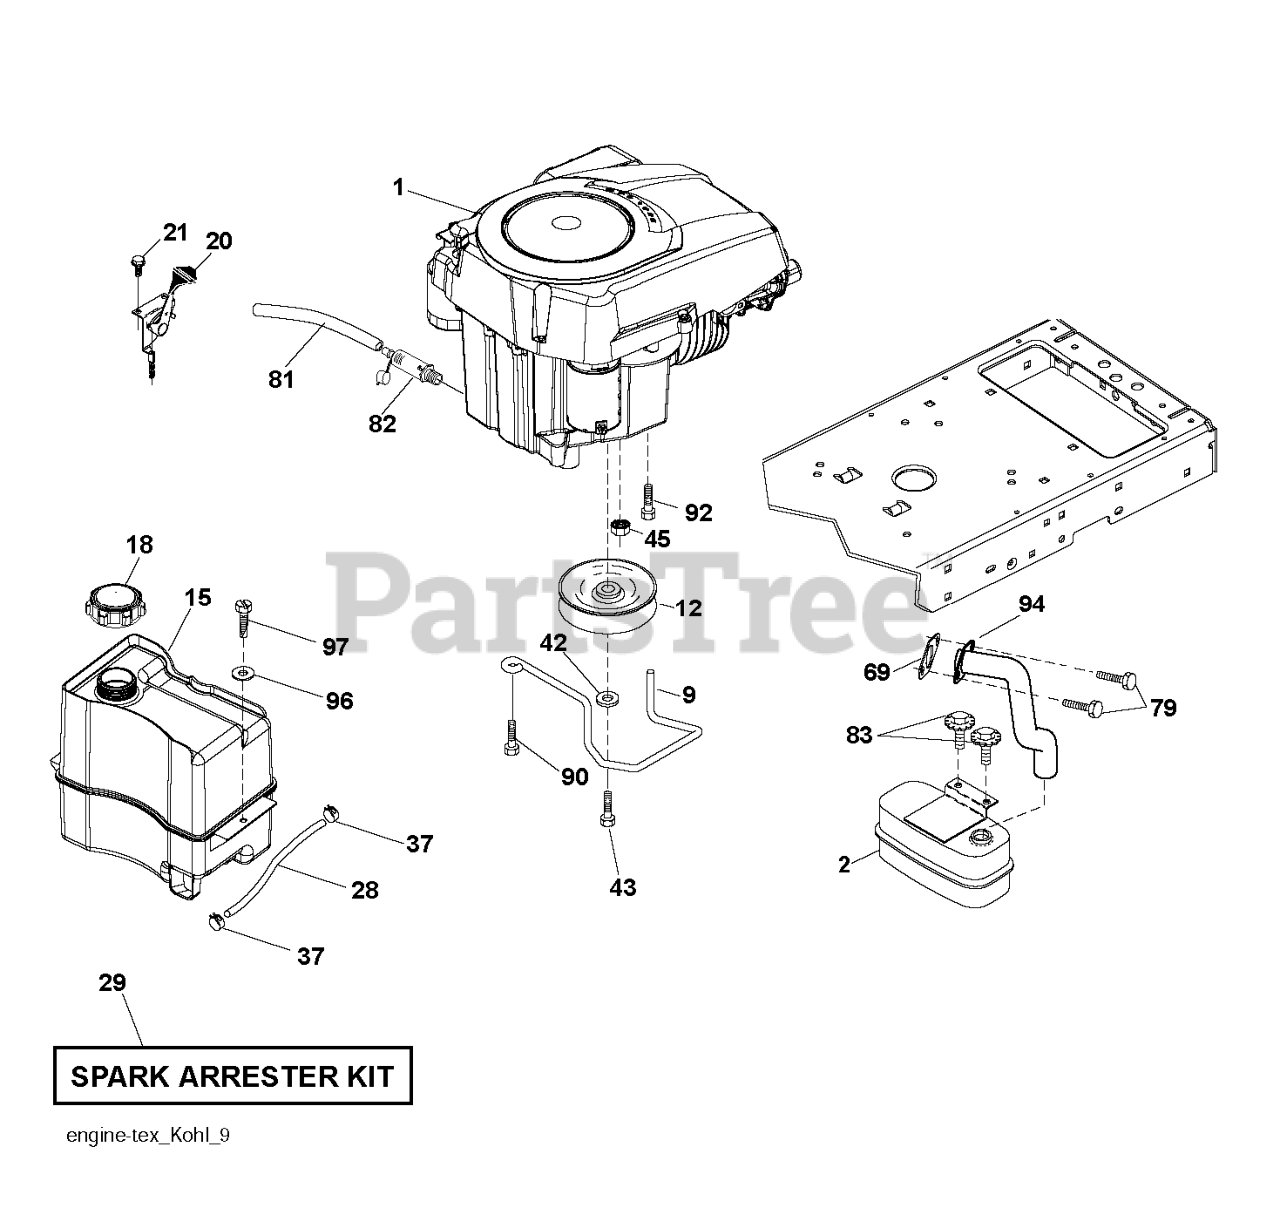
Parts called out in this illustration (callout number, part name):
2	MUFFLER.SINGLE.CYL.KOHL/B&S
9	KEEPER.BELT.ENGINE.4.2
12	PULLY ENGINE
15	RP TANK FUEL FRT 1.5 GAL
18	FUEL CAP
20	CONTROL.TH/CK.C.
21	SCREW.#10 X 0.750.BOS
28	LINE.FUEL.20
29	KIT.SPARK ARRESTOR 794945 B&S
37	HOSE CLAMP
42	LOCKWASHER
43	BOLT HEX 7/16-20X4-1/4"
45	NUT
69	GASKET.EXHAUST.KOHLER
79	SCREW.SOCKET HD.5/16-1
81	TUBE, DRAIN OIL ASM.
82	PLUG DRAIN OIL EASY
83	BOLT.5/16-18UNCX3/4 W/SEMS.BLK
90	SCREW 3/8-16X1
92	SCREW 3/8-16X1
94	RP.TUBE.EXHAUST.KOHL.COURAGE
97	SCREW HEXWSHR 1/4-20X3/4
